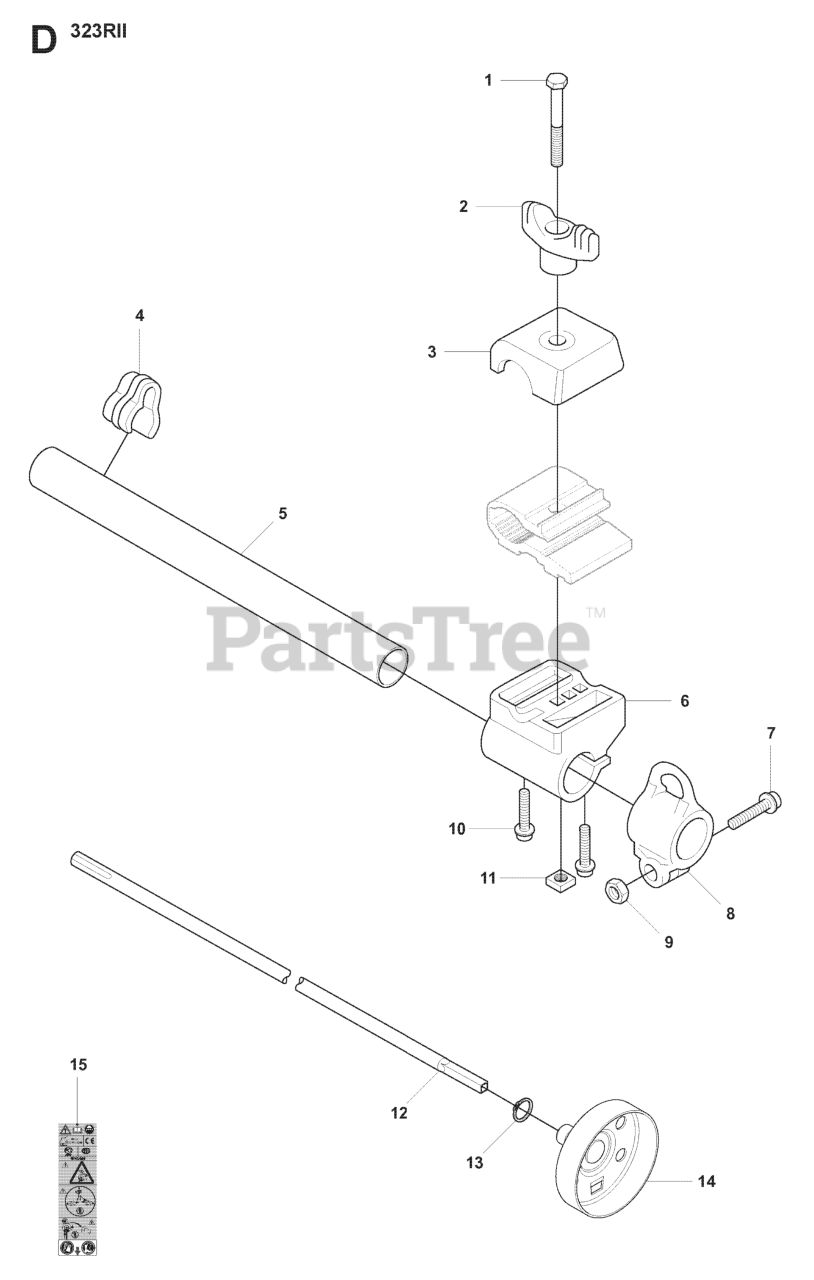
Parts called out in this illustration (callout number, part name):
5	DRIVE TUBE ASSEMBLY
7	SCREW
8	HARNESS HOLDER
12	DRIVE SHAFT
13	RETAINING RING SGA 10
14	CLUTCH DRUM
15	RP WARNING DECAL
